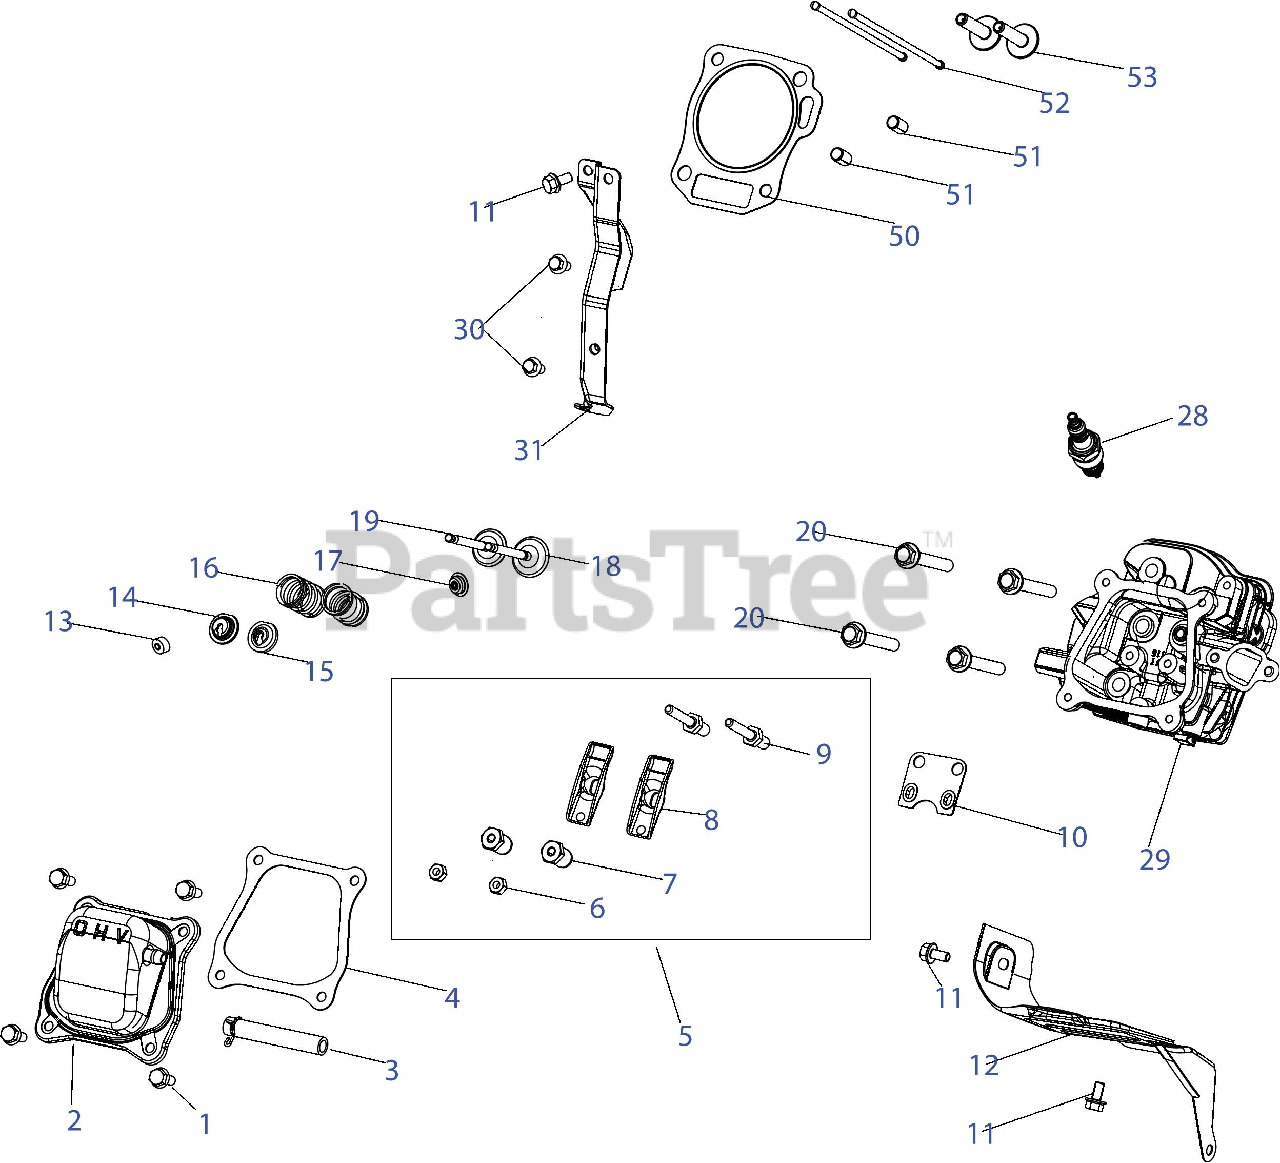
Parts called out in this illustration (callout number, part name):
1	Bolt, M6x16
2	Valve Cover
3	Breather Hose
4	Gasket, Valve Cover
5	Rocker Arm Assembly
7	Adjust Nut
8	Rocker Arm
10	Rocker Arm Base
11	Bolt, M6x12
13	Valve Adjust Cap, Exhaust
14	Valve Spring Seat
15	Valve Spring Seat
16	Valve Spring
17	Intake Valve Seal
18	Intake Vavle
19	Exhaust Valve
20	Bolt, M8x55
28	Spark Plug
29	Cylinder Head
30	Bolt, M6x12
31	Snow Guard
50	Gasket, Cylinder Head
51	Pin, 10x16
52	Push Rod
